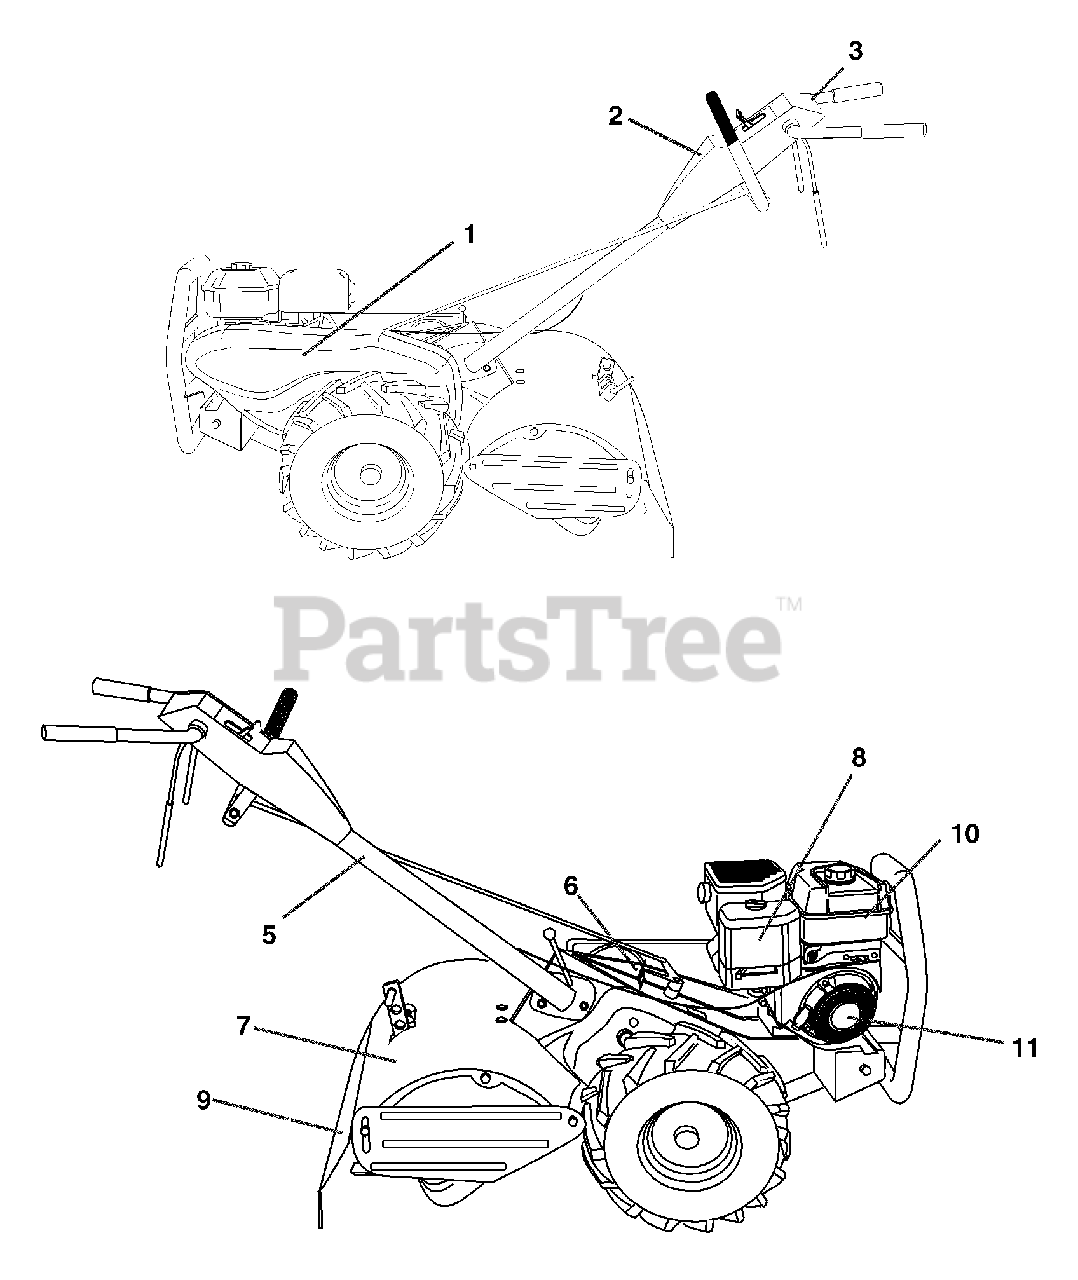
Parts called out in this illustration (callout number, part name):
1	Decal, Blt Grd
2	Decal, CNTRL PNL
3	Decal, Logo
5	Decal, Hand Placement
6	Decal, Shift Indicator
7	Decal, Warning
8	Decal, Engine B&S 6.5 HP
9	Decal, Warning, Rotating Tines
10	Decal, Engine Intek REF
11	Decal, Rewind Intek #274350
